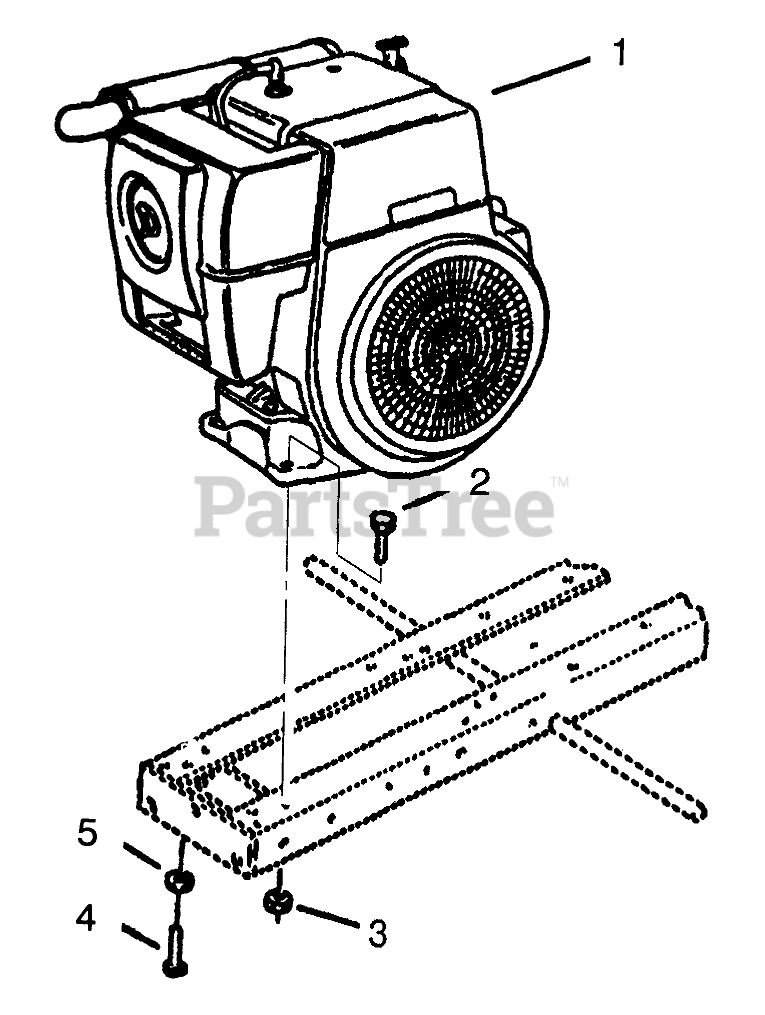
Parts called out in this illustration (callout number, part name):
2	SCREW-HH
3	NUT-LOCK, NI
4	SCREW-HH
5	WASHER-LOCK
